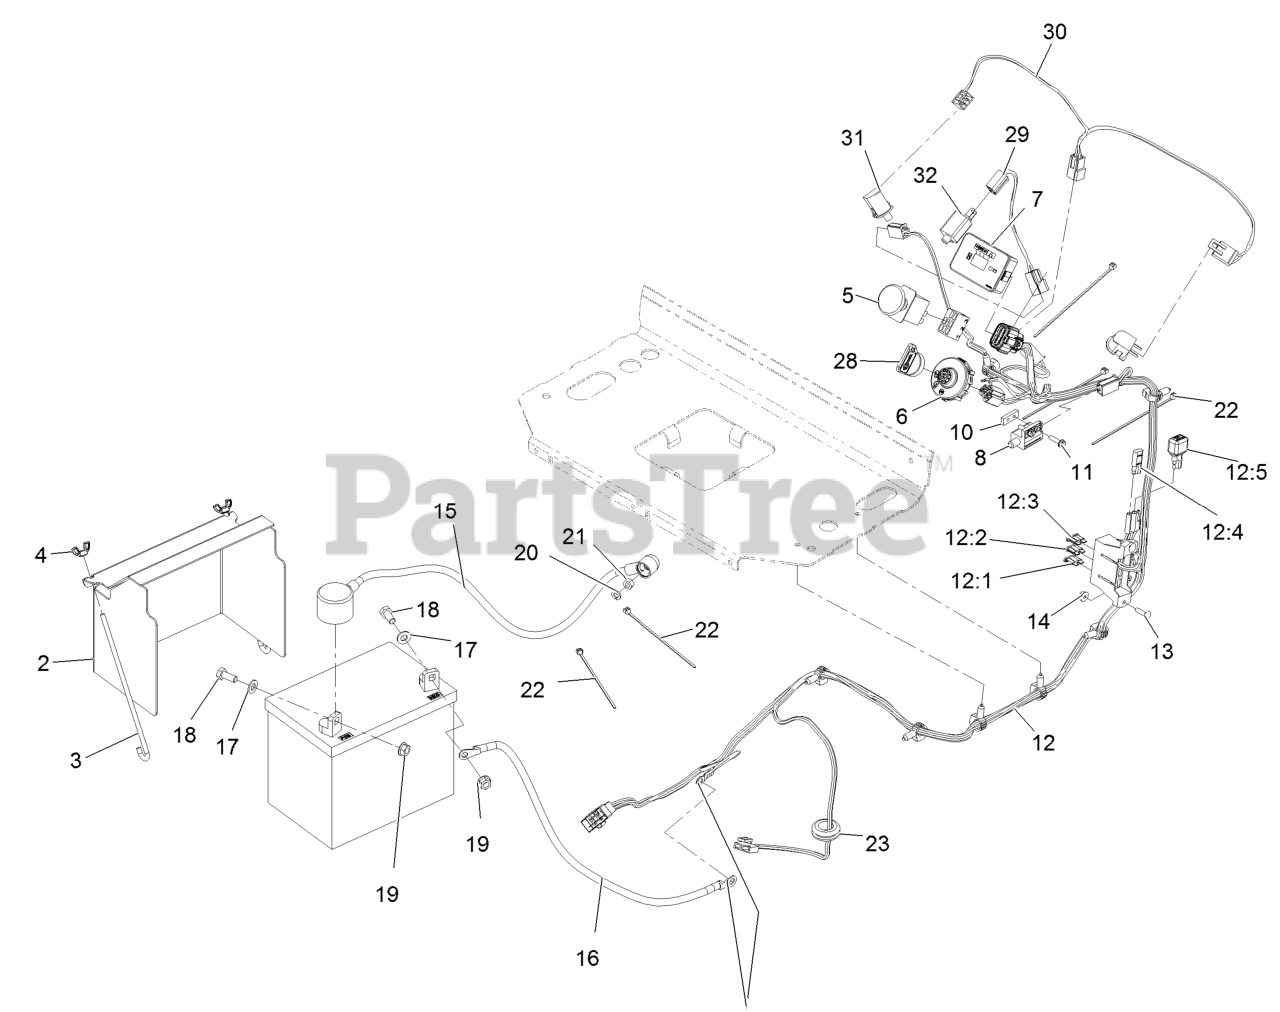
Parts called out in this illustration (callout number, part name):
2	COVER-BATTERY
3	BOLT-HOLDDOWN
4	WINGNUT
5	SWITCH-PTO, ON-ON
7	MODULE-HOUR METER
8	SWITCH-CLOSED, NORMALLY
10	PLATE-TAPPED
11	SCREW-HWH
12	HARNESS-WIRE
12:1	FUSE-BLADE, 30 AMP
12:2	FUSE-BLADE, 25 AMP
12:3	FUSE-BLADE, 10 AMP
12:4	CAP-PLUG
13	SCREW-CARR
15	CABLE-BATTERY, POSITIVE
16	CABLE-BATTERY, BLACK
17	WASHER-PLAIN
18	SCREW-HH
19	NUT-HHF, SMOOTH
20	SCREW-HH
21	NUT-HEX
22	TIE-CABLE
23	GROMMET
28	KEY-IGNITION
29	HARNESS-NEUTRAL
30	HARNESS-OPC
31	SWITCH-BAIL
32	SWITCH-OPEN, NORMALLY
